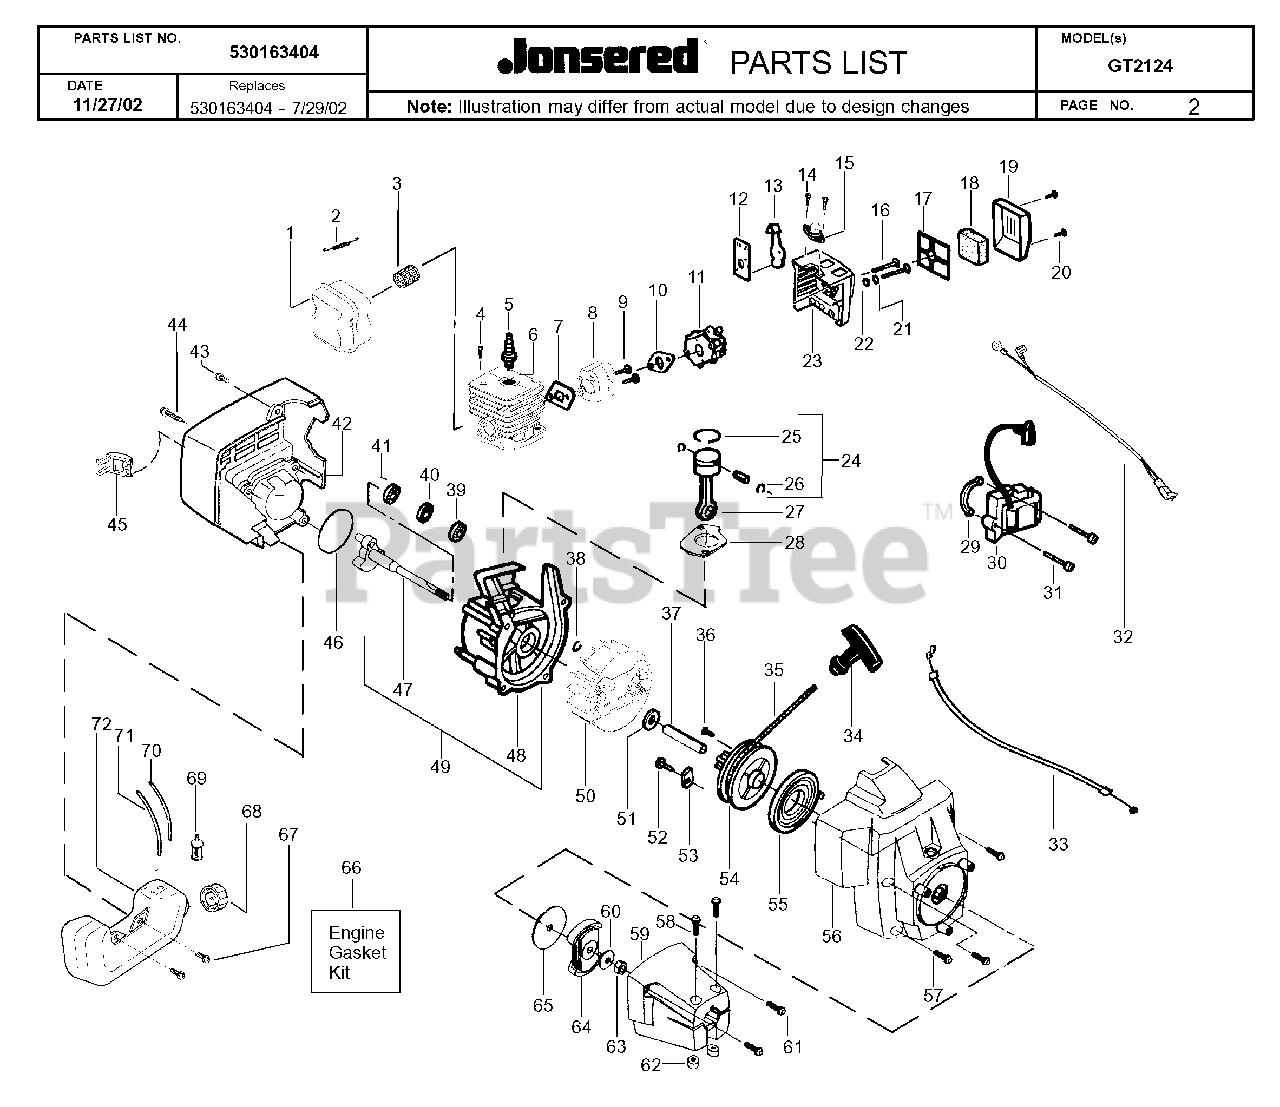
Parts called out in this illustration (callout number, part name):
1	KIT-MUFFLER
5	PLUG-SPARK (RCJ-6Y)
7	GASKET KIT
9	SCREW - CARB. ADAPTOR
10	GASKET KIT
12	CHOKE PLATE
13	CHOKE SHUTTER
15	AIR PURGE BUBBLE
17	FILTER PLATE
18	AIR FILTER FOAM
19	AIR FILTER COVER
20	SCREW FILTER PLATE
21	CHOKE SPACER
24	PISTON
25	PISTON RING
26	WRIST PIN RET.
28	GASKET KIT
29	SPACER - IGNITION MODULE
30	IGNITION MODULE
32	LEAD WIRE ASSEMBLY
34	HANDLE-STARTER
38	RETAINING RING
39	OUTER BEARING
40	KIT-CRANKCASE SEAL
41	BEARING
44	SCREW - SHROUD
46	GASKET KIT
47	CRANKSHAFT ASSEMBLY
48	CRANKCASE
50	FLYWHEEL
52	SCREW 8-16 X 9/16 (PLAS
54	STARTER PULLEY KIT
55	STARTER SPRING
57	SCREW - SHROUD
58	SCREW-10-24 X 1-3/8 (UN
59	CLUTH COVER
60	WASHER FLAT
61	SCREW-10-14 X 13/16 (PL
62	LOCKNUT-HEX 10-24
64	CLUTCH ASSEMBLY KIT
65	FRICTION DISC,CLUTCH 36/41
66	GASKET KIT
68	CAP ASSY W/ RETAINER
69	FUEL PICK-UP ASSY
530069998	CARBURETOR
530071639	CARBURETOR
